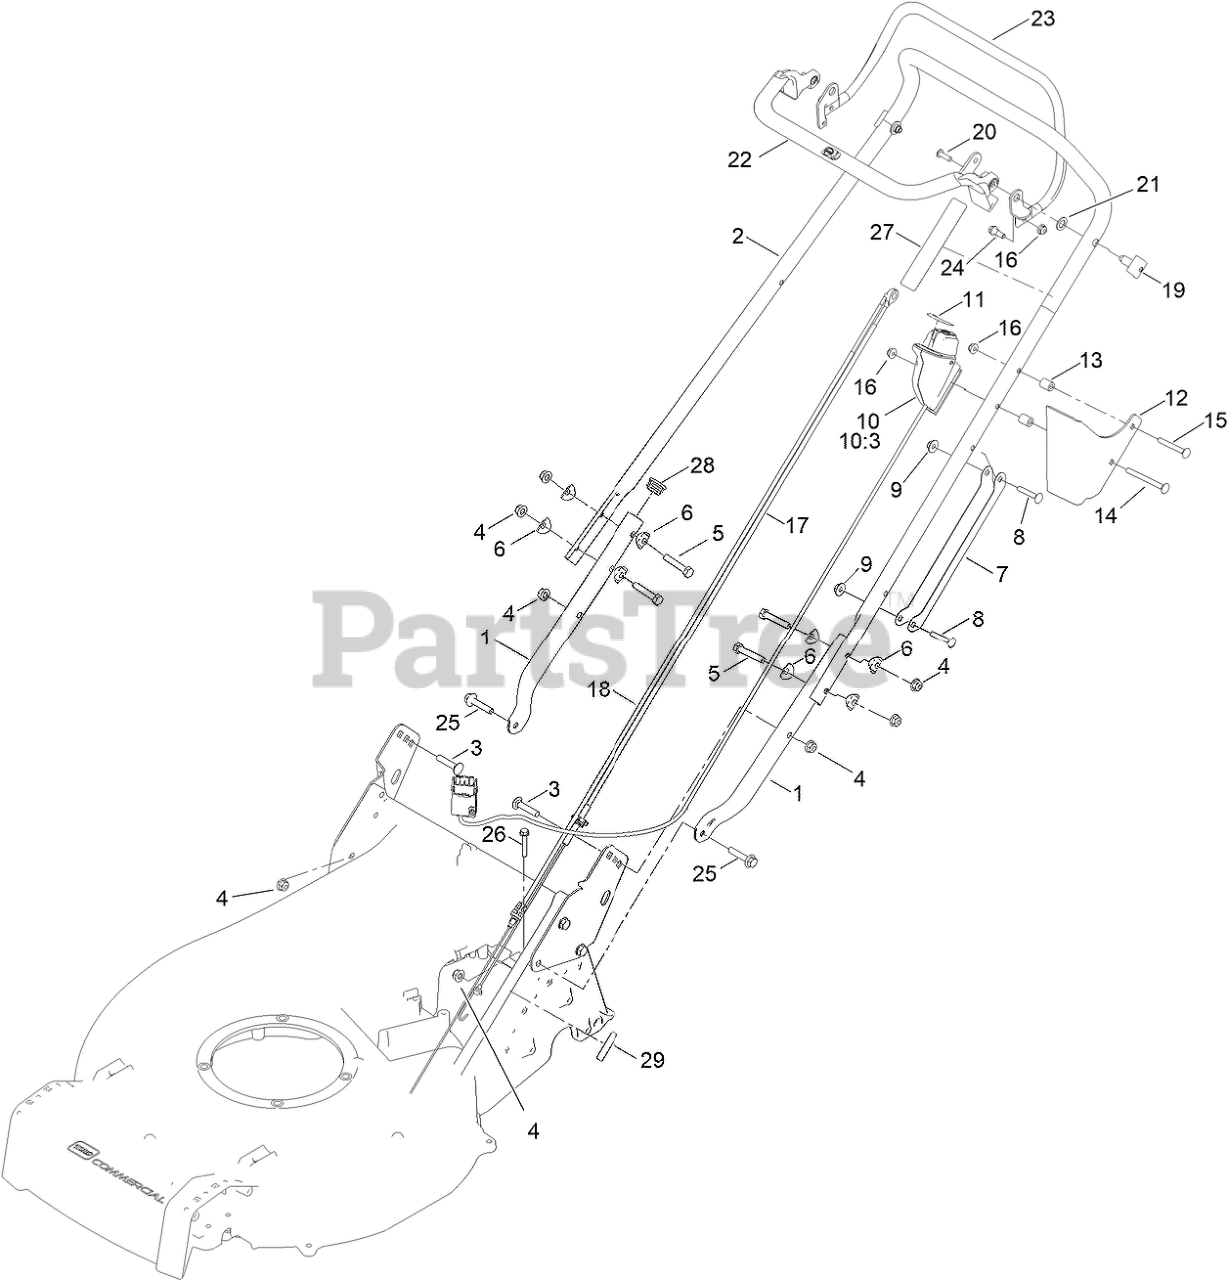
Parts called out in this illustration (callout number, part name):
1	LOWER HANDLE
2	UPPER HANDELEBAR
3	BOLT-CARR
4	NUT-HF, NI
5	SCREW-HH
6	WASHER-CUP
7	GUARD-CABLE, HANDLE
8	SCREW-CARR
9	NUT-HF
10	STARTER SWITCH ASM
10:3	STARTER BUTTON SERVICE ASM
11	DECAL CONTROL SPEED
12	GUARD-HOUSING, SWITCH
13	SPACER
14	SCREW-CARR
15	SCREW-CARR
16	NUT-HF
17	CABLE-TRACTION, 60V
18	CABLE-BRAKE
19	PIN-PIVOT
20	SCREW
21	WASHER-NYLON
22	OPC LEVER - ENGINE
23	LEVER-CLUTCH, GEARBOX
24	BOLT-SHOULDER
25	SCREW-HHF
26	SCREW-HWH
27	DECAL-CONTROLS (60V START)
28	PLUG-ROUND TUBE, 1 IN.
